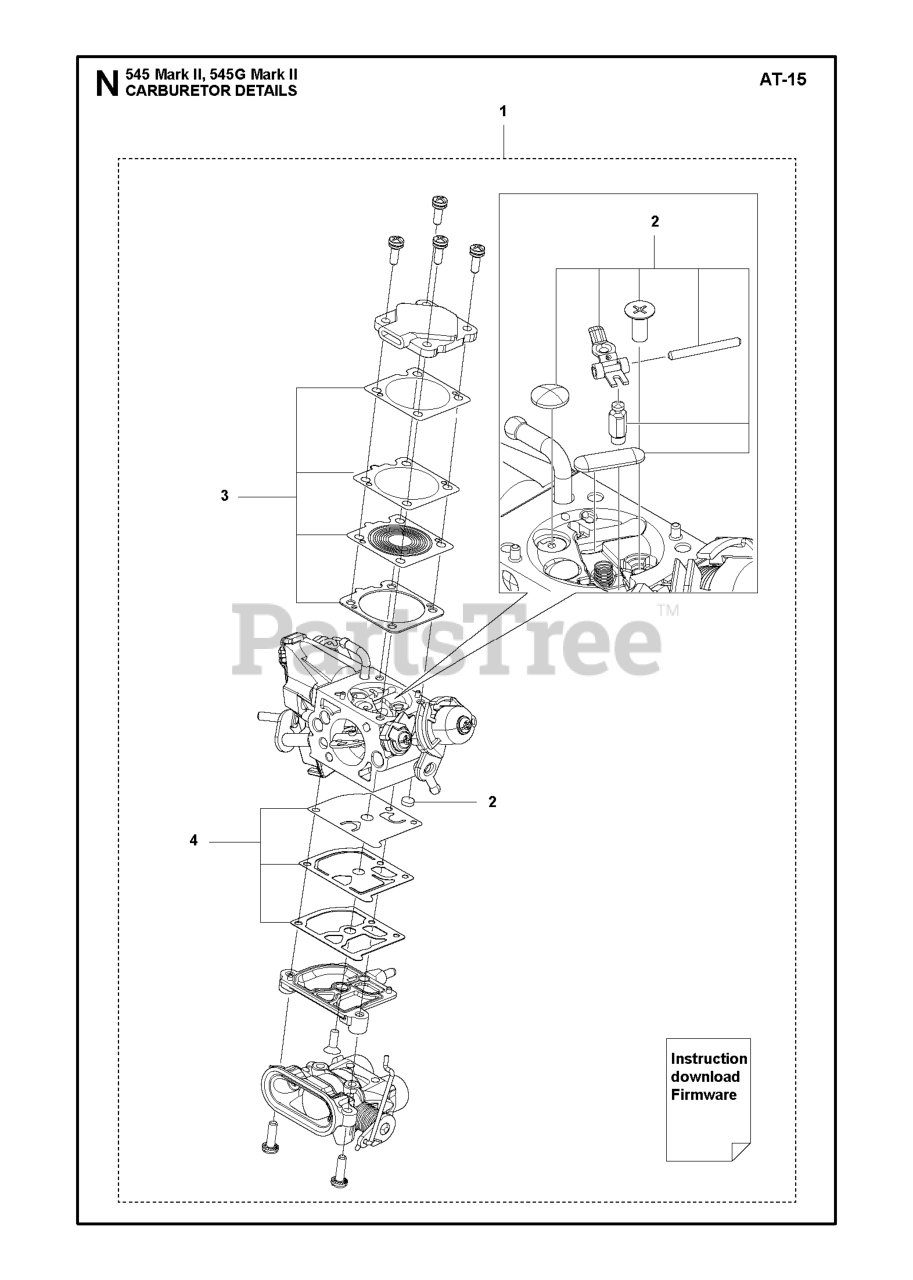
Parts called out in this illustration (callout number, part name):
1	CARBURETTOR KIT AT-15 H545/545
2	GASKET KIT
3	DIAPHRAGM & GASKET KIT AT SPIR
4	GASKET KIT CARBURETOR
